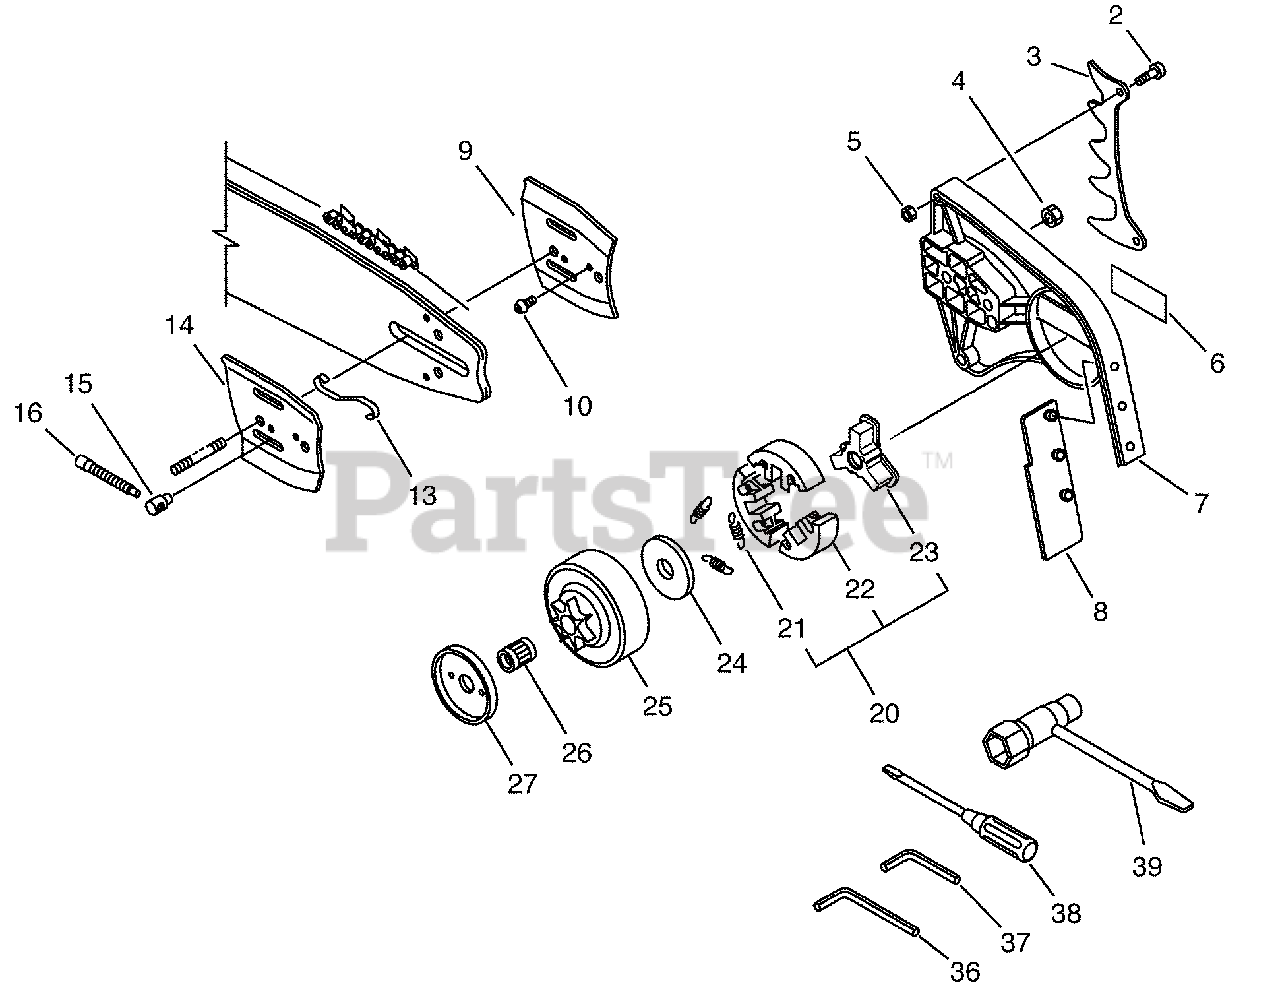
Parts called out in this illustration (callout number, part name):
2	BOLT 6×20
3	SPIKE, BUMPER
4	NUT, FLANGE
5	NUT, LOCK
6	LABEL - ECHO
7	GUARD, SPROCKET
9	PLATE, GUIDE - OUTER
10	SCREW 3×6
13	HOLDER, PLATE
14	PLATE, GUIDE - INNER
15	TENSIONER, CHAIN
16	SCREW, CHAIN TENSION
20	CLUTCH ASSY
21	SPRING, CLUTCH
22	CLUTCH SHOE SET
23	HUB, CLUTCH
24	PLATE, CLUTCH
25	DRUM, CLUTCH
26	BEARING, NEEDLE
36	WRENCH, ALLEN 5 MM
37	WRENCH, ALLEN 4 MM
38	SCREWDRIVER, SLOTTED
39	WRENCH, T 17×19 MM
